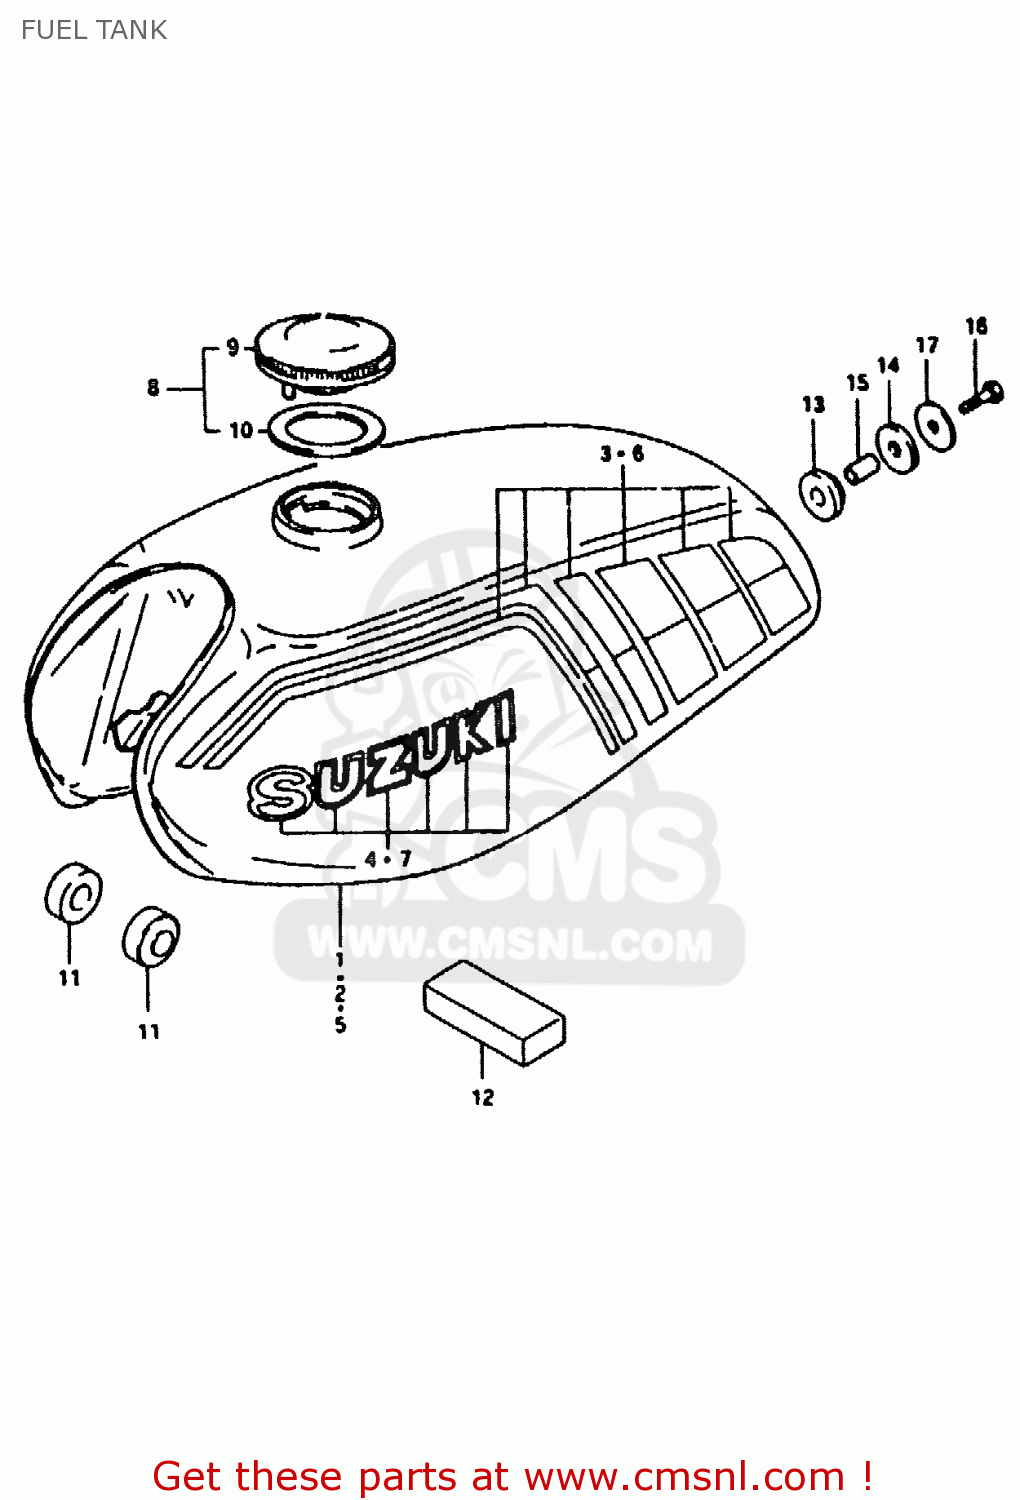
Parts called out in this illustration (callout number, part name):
1	TANK, FUEL (BLUE)
2	TANK, FUEL (RED)
3	TAPE SET
4	EMBLEM
5	TANK, FUEL (WHITE)
6	TAPE SET
7	EMBLEM (BLUE)
8	CAP ASSY,FUEL TANK FILLER
9	CAP,FUEL TANK
10	GASKET (NAS)
11	CUSHION
12	CUSHION
13	CUSHION
14	CUSHION
15	SPACER(8.5X12X19)
16	BOLT (8X30)
17	WASHER (8.5X29X1.6)
